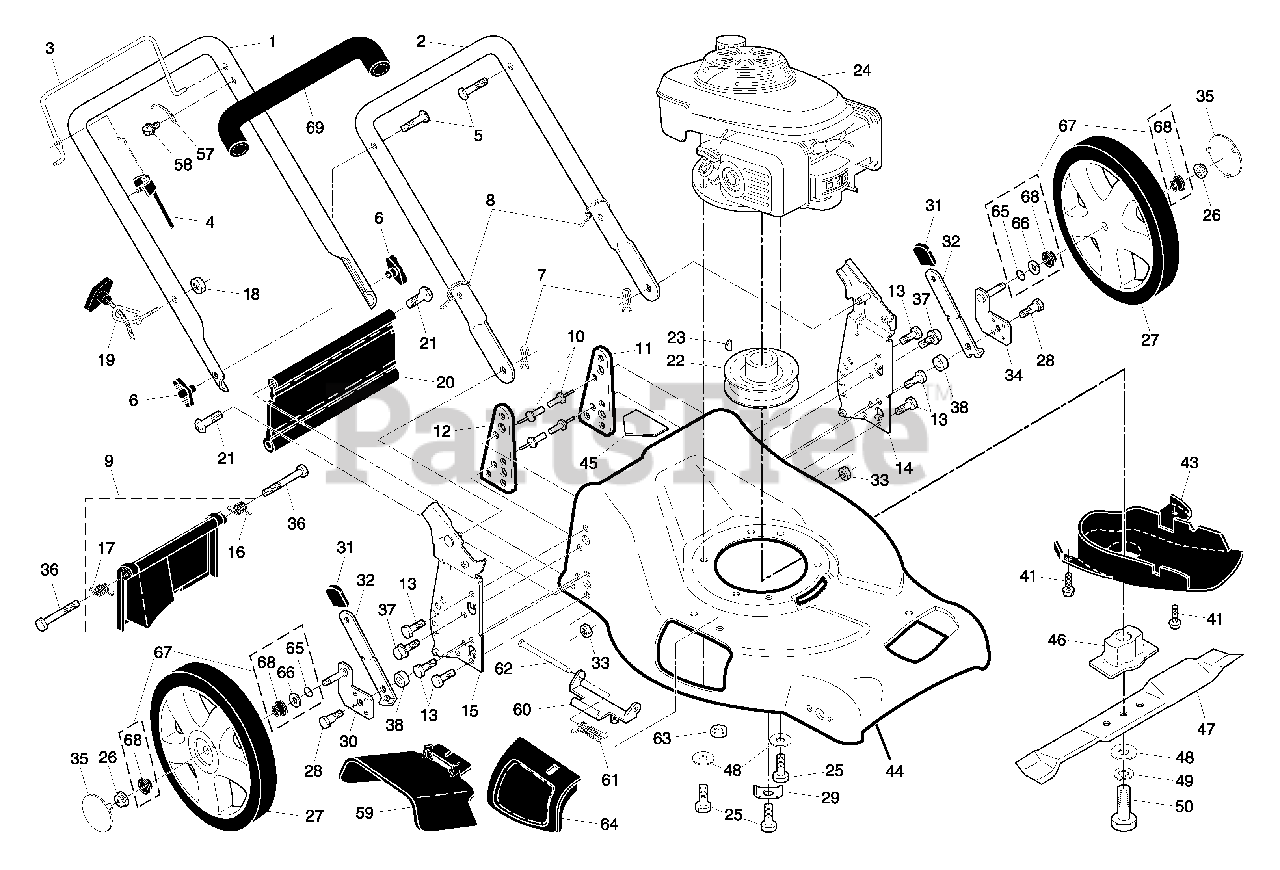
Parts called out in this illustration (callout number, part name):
1	Upper Handle
2	Lower Handle
3	Control Bar
4	Engine Zone Control Cable
5	Handle Bolt
6	Handle Knob
7	Hairpin Cotter
8	Wire Tie
9	Kit, Rear Door
11	Support Bracket, LH
12	Support Bracket, RH
13	Screw 1/4-20 x 5/8
14	Handle Bracket Assembly, LH
15	Handle Bracket Assembly, RH
16	Spring, LH
17	Spring, RH
18	Keps Locknut 1/4-20
19	Rope Guide
20	Rear Skirt
21	Screw, Tapping 1/4-20 x 1/2
22	Engine Pulley
23	Key, Hi-Pro
25	Hex Head Thread Rolling Screw 3/8-16 x 1-1/8
26	Hex Flange Nut
27	Wheel & Tire Assembly, Rear, 14"
28	Shoulder Bolt 5/16-18 x .33
29	Washer, Engine, Zinc-Plated
30	Axle Arm Assembly, RR
31	Selector Knob
32	Selector Spring
33	Nut, Hex 5/16-18
34	Axle Arm Assembly, LR
35	Hubcap
37	Thread Cutting Screw w/Sems 5/16-18 x 3/4
41	Screw
43	Debris Shield
44	Kit, Lawn Mower Housing
45	Danger Decal
46	Blade Adapter
47	Blade, 21"
48	Hardened Washer
49	Helical Washer 3/8-24 x 1-3/8 Grade 8
50	Hex Head Machine Screw 3/8-24 x 1-3/8 Grade 8
57	Upstop Bracket
59	Discharge Deflector
60	Hinge Bracket
61	Spring
63	Nut, Hex
64	Mulcher Door
65	O-Ring
66	Washer, Flat 1/2
67	Kit, Bushing
68	Bushing, Nylon, Black
69	Grip, Foam
